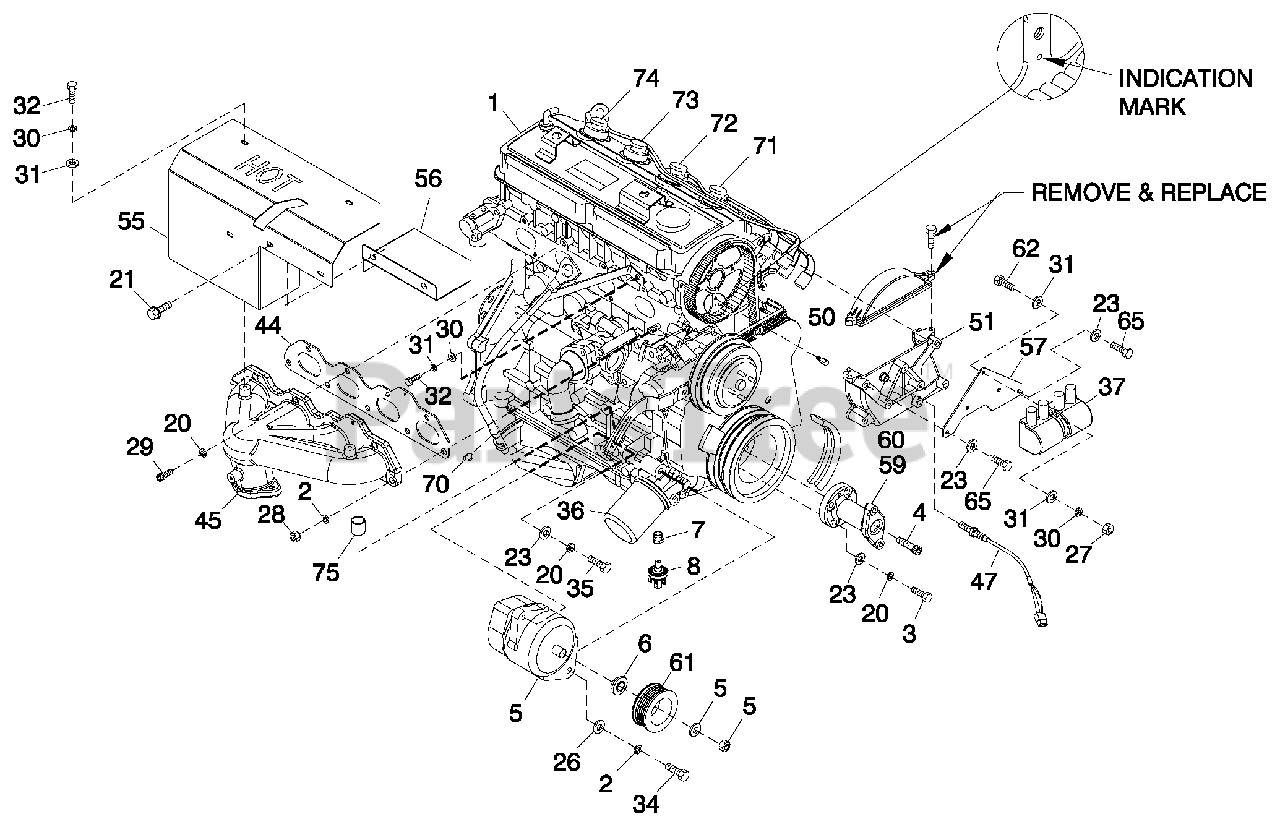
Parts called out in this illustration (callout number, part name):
1	WELDMENT RADIATOR SUPPORT C2
2	RADIATOR 598 X 568 X 49 CPL RH
3	V-BELT 31/64" X 57-3/8"
4	WASHER LOCK M10
5	SCREW HHC M10-1.5X 30 G10.9
6	BRACKET, SIGNAL CONDITIONER (USED ONLY WITH QTA PRODUCT)
7	SHIELD RADIATOR C4
8	HOSE 9/32 ID (27"LG)
9	PULLEY FAN V-GROOVE 9"
10	FAN COOL 22" DIA 10 BLADE LH
11	ARM BELT TENSIONER
12	SHOULDER BOLT 1/2 X 2-1/4"
13	SPRING TENSION CPL
14	PULLEY V-BELT 4" FLANGED
15	WASHER FLAT 3/8-M10 ZINC
16	PROBE, COOLANT LEVEL 3/8NPTF
17	CLAMP HOSE #28 1.32-2.25
18	HUB FLEX PLATE
19	WASHER FLEX (THIN)
20	TAPE FOAM 1 X 1 (26.75" LG)
21	DISK FLEX
22	NUT HEX LOCK 5/16-24 NY INS
23	WASHER FLAT 1/4-M6 ZINC
24	SCREW HHC 5/16-24X1.124
25	WASHER LOCK M6-1/4
26	TANK COOLANT RECOVERY
27	CLAMP HOSE BAND 1/4
28	BEARING #6205 2NSE C3 E SRI2 S
29	PULLEY 4.5" DIA MACHINED
30	SCREW HHC M10-1.5X30 G8.8
31	SCREW HHC 1/2-13X2" G8
32	WASHER FLAT 1/2 ZINC
33	WASHER LOCK 1/2
34	NUT HEX 1/2-13 STEEL
35	SCREW HHFC M8-1.25 X 20 W/M6
36	CLAMP HOSE #24 B1.06-2.00
37	SHAFT FAN DRIVE
38	RETAINER BEARING
39	WASHER FLAT 5/16-M8ZINC
40	WASHER LOCK M8-5/16
41	SCREW HHC M8-1.25X 45 C8.8
42	KEY WOODRUFF 4 X19D
43	HOSE LOWER RADIATOR G2
44	HOSE UPPER RADIATOR G2 (USED WITH MANFLD P/N 0G0707)
45	NUT HEX M6X1.0 G8 YELCHR
46	SPACER .5X1.5X.25STL/ZINC
47	SCREW HHFC M6-1.0X20 G8.8
48	SCREW THF M6-1 X 16 N WA Z/JS
49	CAP RADIATOR 13 PSI
50	BRACKET COOLANT TANK
51	WASHER NYLON .50 X .87 X .06
52	BRACKET TENSIONER SPRING
53	SCREW HHC M8-1.25X20 C8.8
54	BEARING SLEEVE 1/2/X 3/4X1
55	NUT HEX LOCK M8-1.25 NY INS
56	SPACER CPL COOLING FAN 1/8"
57	ASSY PCB LCL SENSOR (USE WITH I/N 16, P/N 0H1827 ONLY)
59	NUT FLANGE M6-1.0 NYLOK
60	CLAMP HOSE BAND .50
